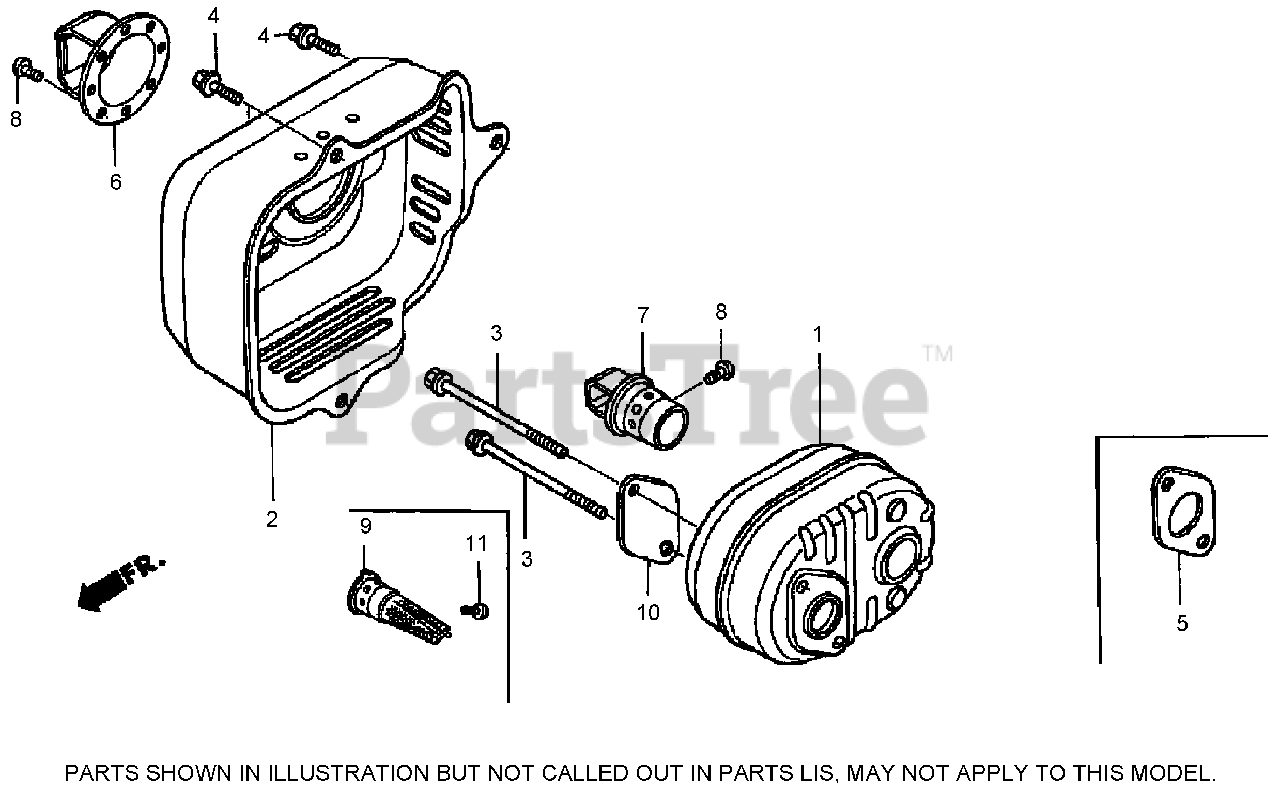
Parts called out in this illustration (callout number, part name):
1	MUFFLER
2	PROTECTOR, MUFFLER (CBU)
3	BOLT, FLANGE (6X79) (CT200)
4	BOLT-FLANGE (6X12)
5	GASKET, MUFFLER
9	ARRESTER, SPARK
10	PLATE, ARRESTER NUMBER
11	SCREW-TAPPING (4X6)
